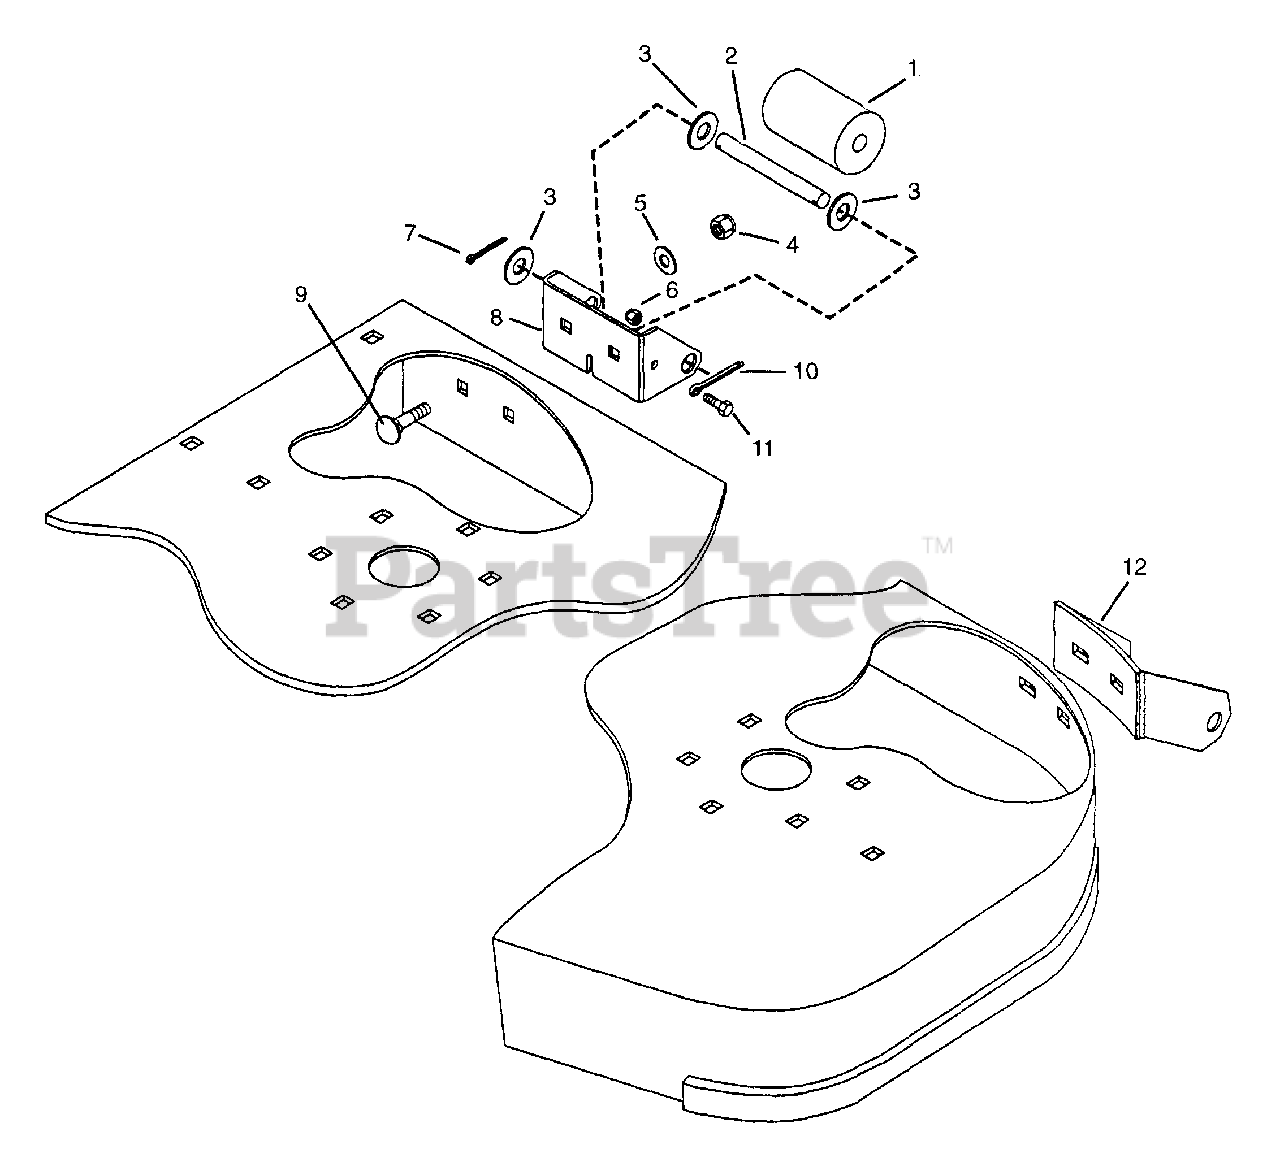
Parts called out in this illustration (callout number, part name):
1	Roller, Gauge
2	Rod
3	Washer-Flat-Steel .656 x 1.312 x .095
4	Nut-Locking-Nylon .375-16 w/ Insert Grade 2
5	Washer-Flat-Steel .406 x .812 x .065
6	Nut-Hex .250-20 Grade 2
7	Pin-Cotter .25 x 1.00
8	Bracket, Roller
9	Bolt-Round Head Square Neck .38-16 x 1.0
10	Pin-Cotter .250 x 2.00
11	Bolt-Hex .25-20 x .75 Grade 5
12	Weldment, Roller Bracket
